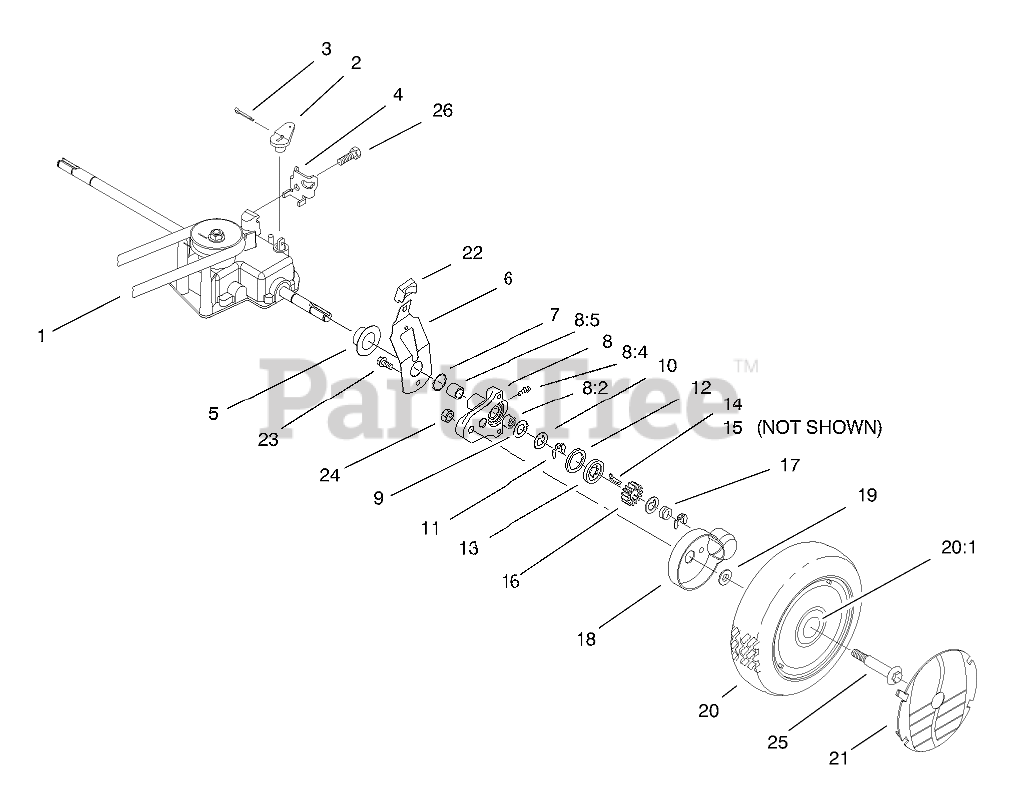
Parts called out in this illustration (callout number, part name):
1	V-BELT E
2	LEVER-SHIFT
3	PIN-COTTER
4	CLAMP-CABLE
5	CAP-END
6	SPRING ARM ASM
7	O-RING
8	PIVOT ARM ASM
8:2	BEARING-ROLLER
8:4	FITTING-GREASE
8:5	BUSHING
9	WASHER-ARM, PIVOT
10	WASHER-THRUST, KEYED
11	RING-CLIP, LOCKING
12	RING-FRICTION
13	WASHER-CLUTCH
14	KEY-ROCKING, LH
15	KEY-ROCKING, RH
16	GEAR-PINION
17	SPRING-COMPRESSION
18	COVER-WHEEL
19	SPACER-COVER, WHEEL
20	WHL & TIRE ASSEMBLY
20:1	BUSHING
21	COVER-WHEEL
22	KNOB-ARM
23	SCREW-HWH
24	NUT-LOCK
25	BOLT-WHEEL
26	SCREW-HWHTF
